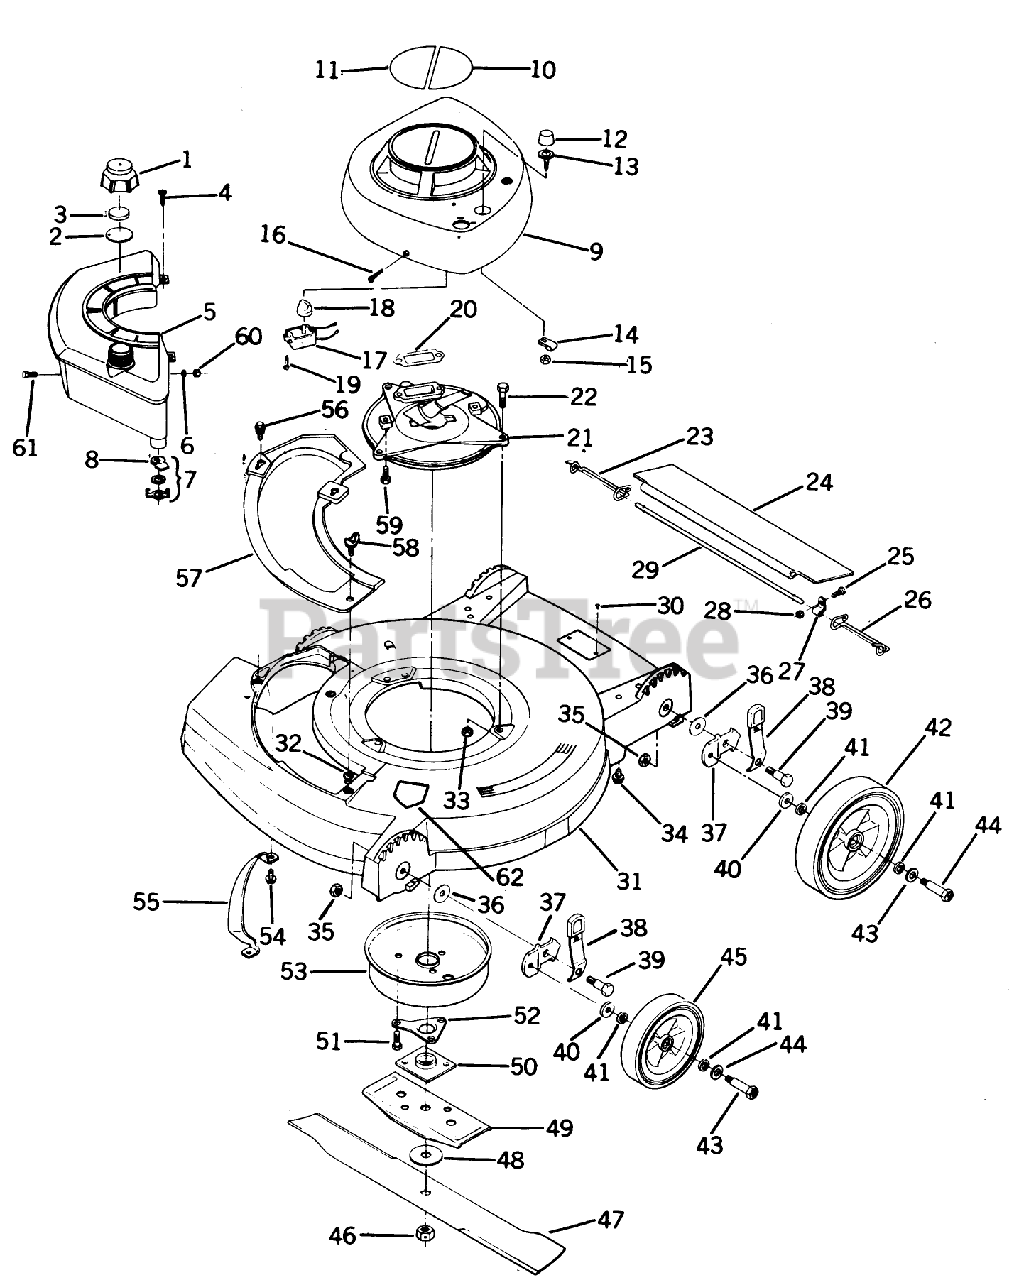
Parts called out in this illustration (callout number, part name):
2	GASKET S
3	BAFFLE - FOAM SM
4	SCREW F
7	SHUT OFF VALVE KIT
15	LOCKNUT S
16	SCREW F
18	SWITCH KNOB
22	SCREW
23	SPRING;TRAILING SHIELD RH
24	SHIELD
26	SPRIG T/SHLD ASOC
27	CLAMP ROD KMC
28	LOCKNUT E
29	ROD 21" ADVANCE
33	NUT-LOCK F
34	SCREW
35	LOCKNUT
36	WASHER
40	WASHER WROUGHT
41	WASHER
43	SPACER
44	BOLT WHEEL
45	WHEEL & TIRE KIT
46	NUT-BLADE
48	WASHER
50	PLATE AND COLLAR ASM
51	SCREW
52	SUPPORT F
55	BAR-TOE
58	WING SCREW LAWRE
59	SCREW V
